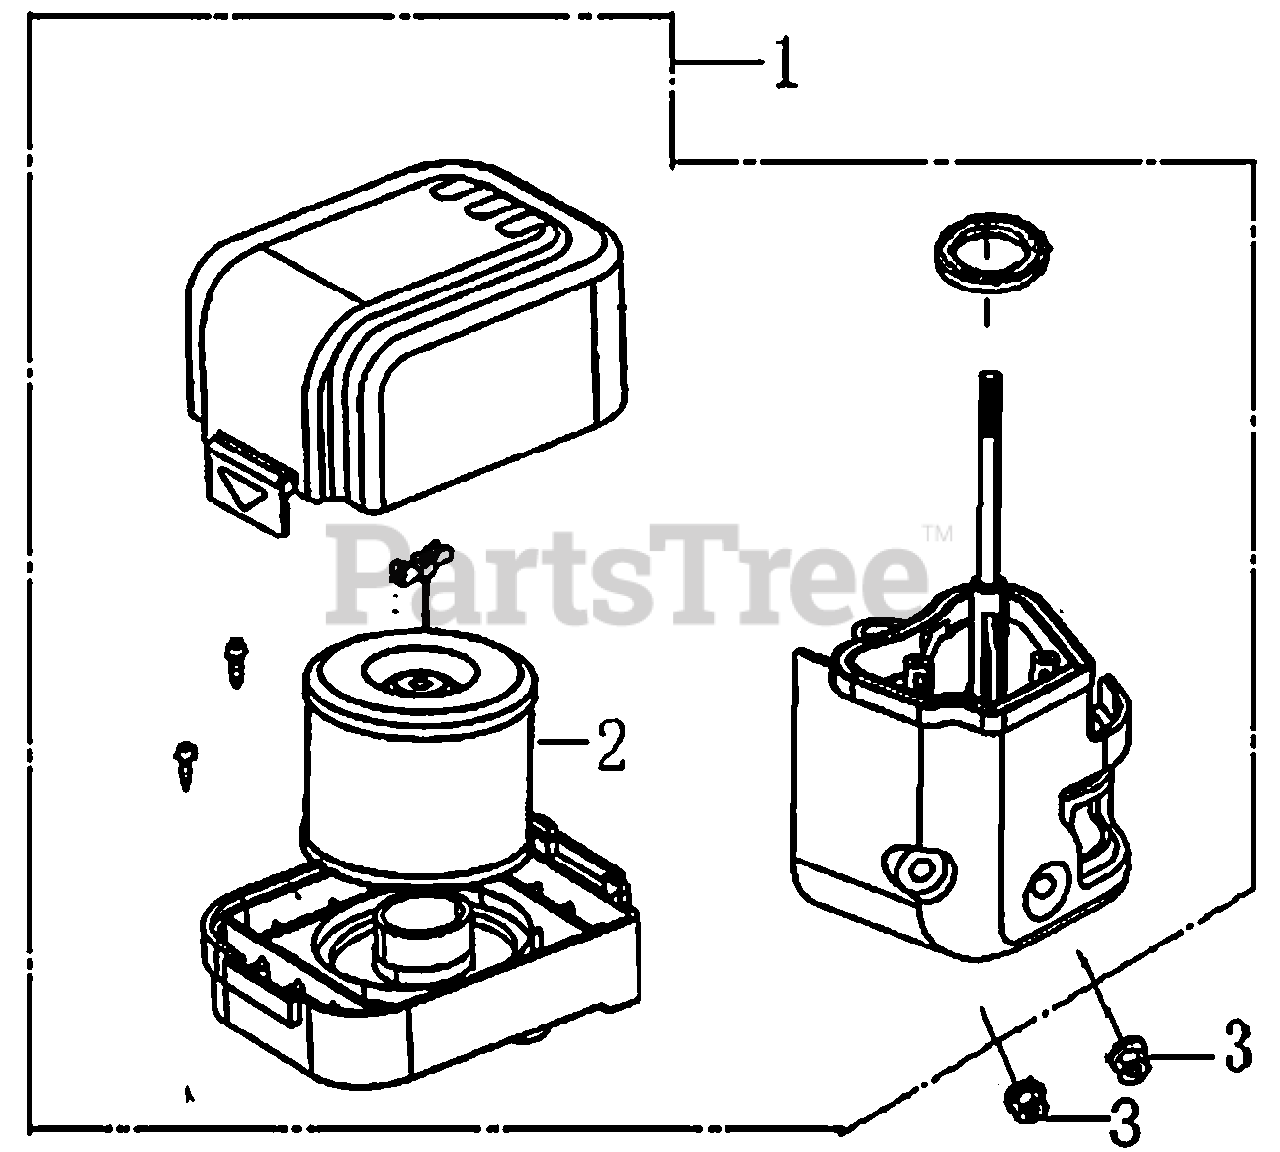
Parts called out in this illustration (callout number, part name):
1	AIR CLEANER ASSY
2	ELEMENT, AIR CLEANER
3	NUT, FLANGE, 6MM
